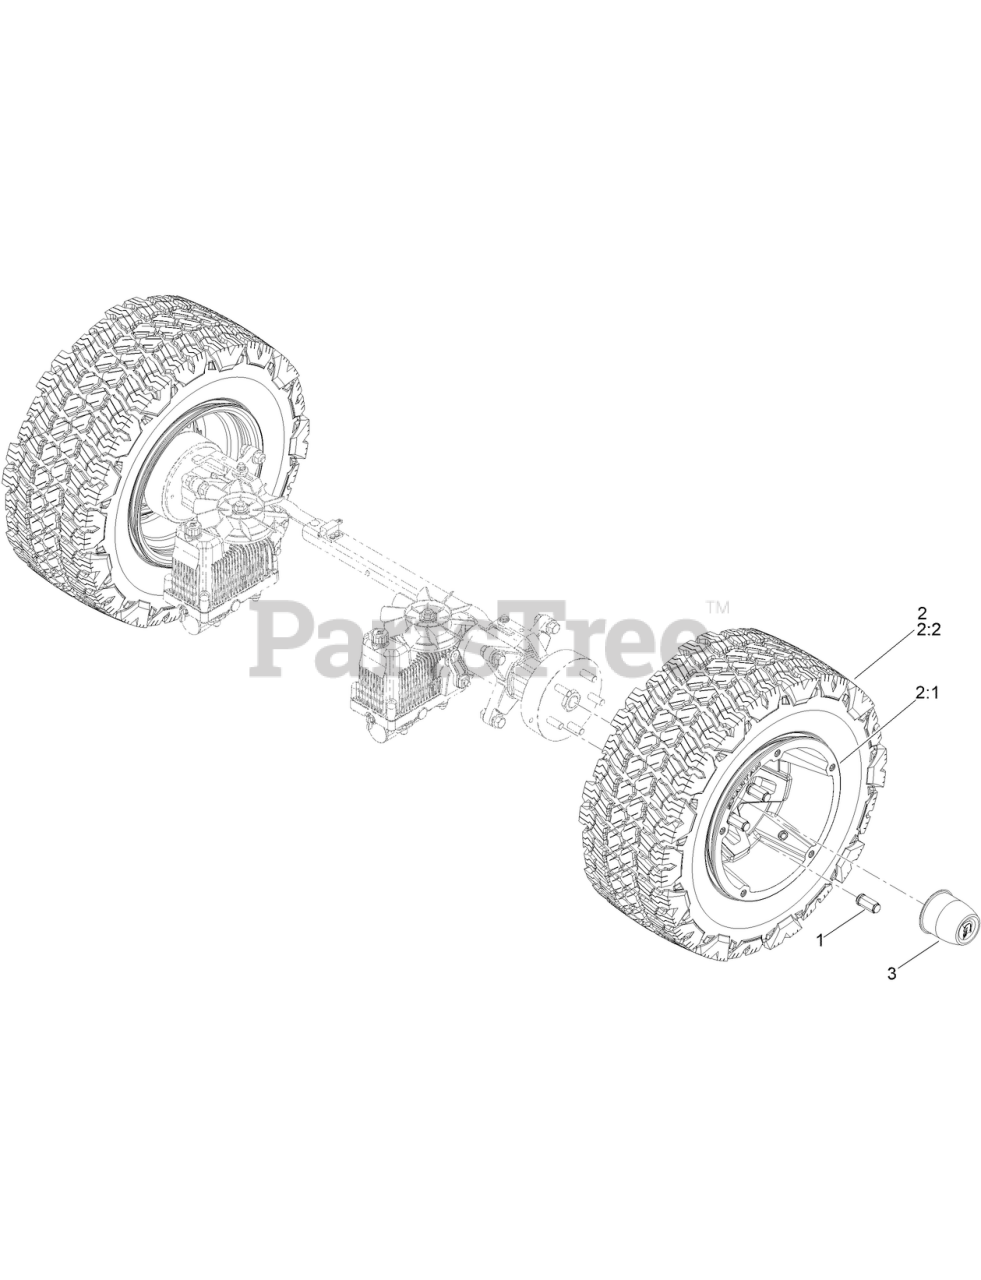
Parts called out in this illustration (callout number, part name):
1	LUG NUTS
2	54 RR WHL ASSM W/VS5010-24X10.50-R12
2:1	7IN STEEL WHEEL
2:2	MWR 24 X 10.5-12 RADIAL TIRE
3	RR STEEL WHEEL SILVER CNTR CAP
